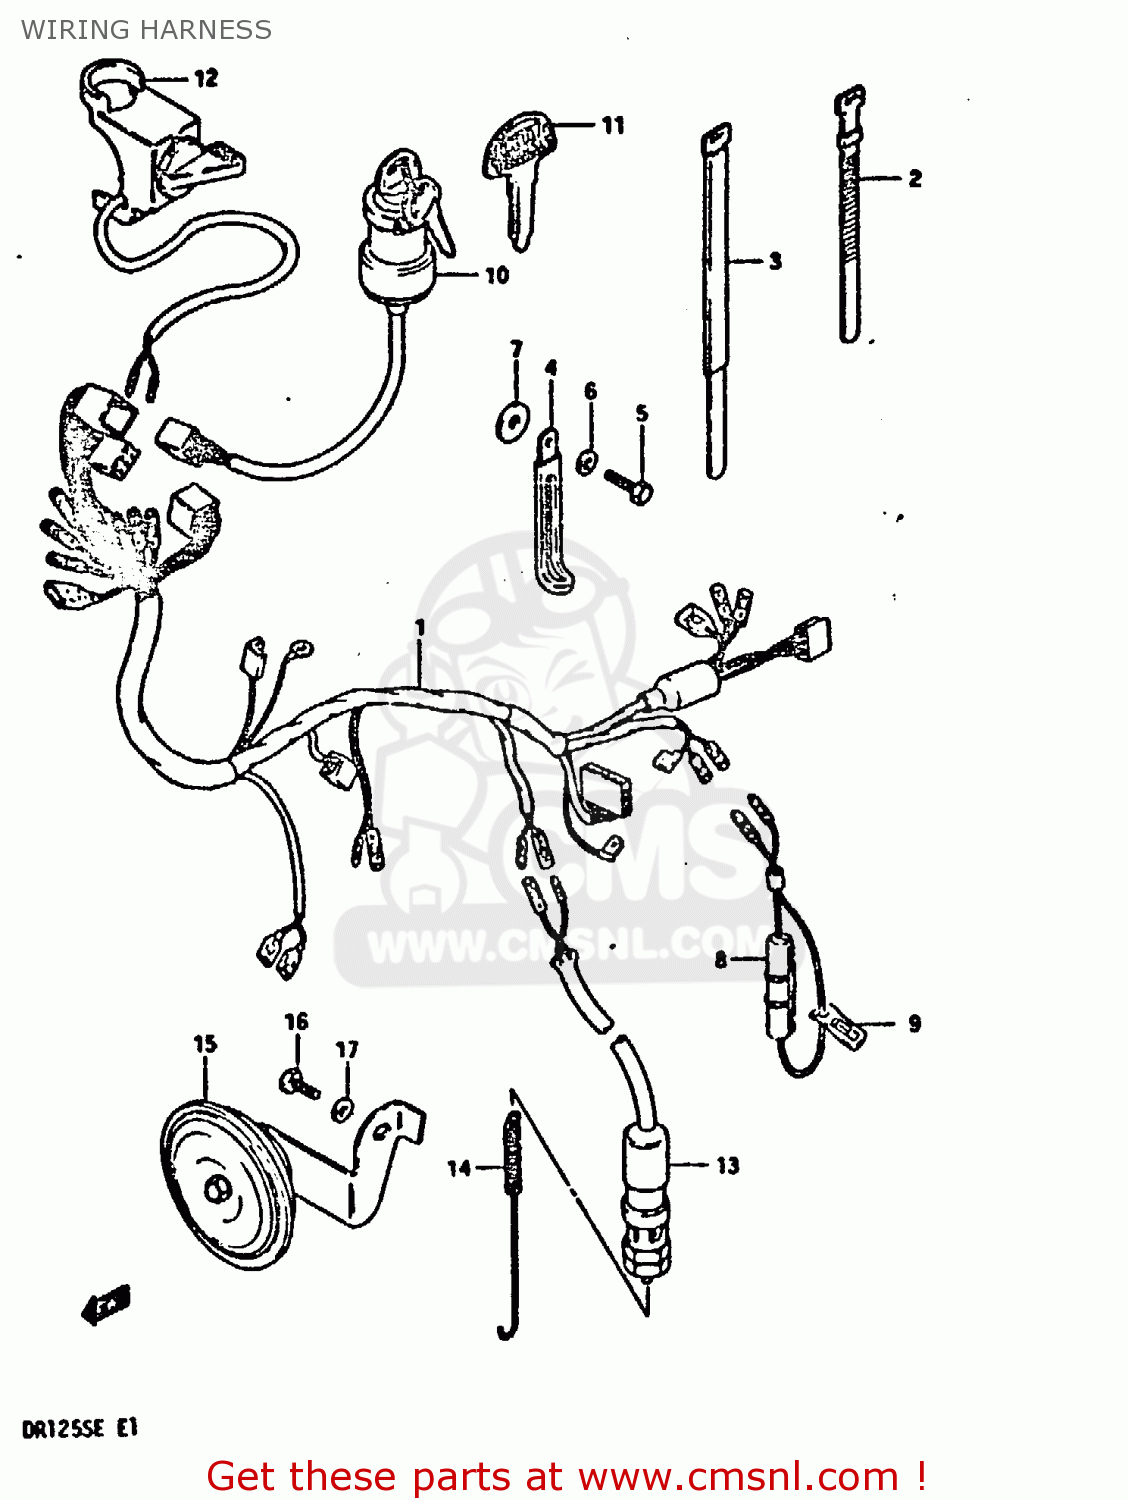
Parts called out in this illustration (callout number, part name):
1	HARNESS,WIRING
2	CLAMP(L:120)
3	CLAMP
4	CLAMP
5	BOLT 6X16
6	WASHER
7	WASHER
8	CASE ASSY,FUSE
9	FUSE(15A)
10	SWITCH ASSEMBLY,IGNITION
11	KEY,BLANK
12	SWITCH ASSY,ENGINE STOP
13	SWITCH ASSY,STOP LAMP
14	SPRING
15	HORN ASSY
16	BOLT
17	WASHER
